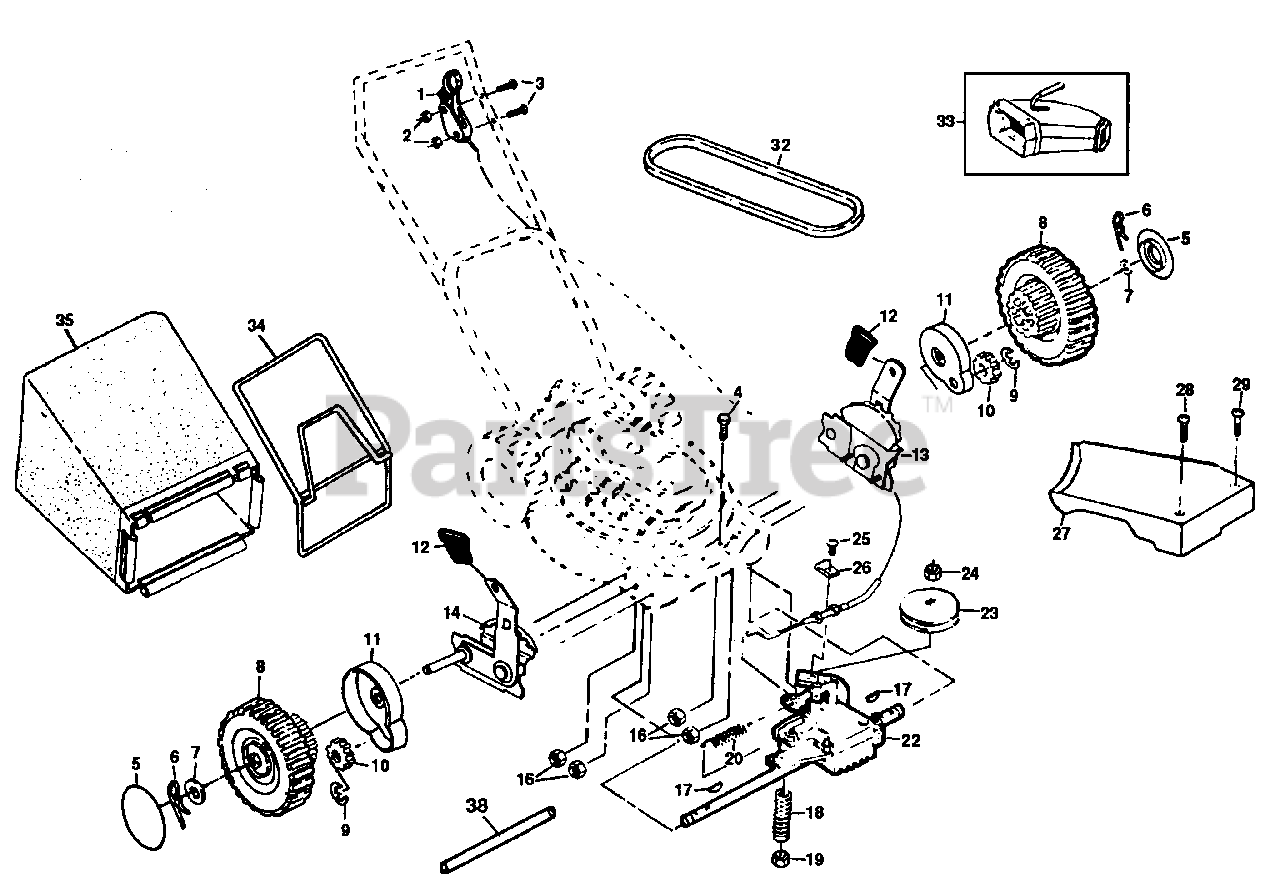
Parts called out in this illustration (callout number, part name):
1	Drive Control (AYP part number)
2	Locknut #10-24 (AYP part number)
3	Pan Head Machine Screw #10-24 x 2 (AYP part number)
4	Hex Head Bolt 1/4-20 x 2-3/4 (AYP part number)
5	Hubcap (AYP part number)
6	Retainer Clip (AYP part number)
7	Washer (AYP part number)
8	Wheel & Tire Assembly 8.00 x 1-3/4
10	Pinion (AYP part number)
11	Dust Cover (AYP part number)
12	Selector Knob
13	Wheel Adjuster Assembly (Left) (AYP part number)
14	Wheel Adjuster Assembly (Right) (AYP part number)
16	Locknut (AYP part number)
17	Woodruff Key #3 (AYP part number)
18	Spring (AYP part number)
19	Locknut 1/4-20 (AYP part number)
22	Gear Case Assembly (AYP part number)
23	Drive Pulley (AYP part number)
24	Locknut (AYP part number)
25	Pan Head Self-tapping Screw #10-24 (AYP part number)
26	Cable Clamp (AYP part number)
27	Drive Cover (AYP part number)
28	Pan Head Machine Screw #10-24 x 2-3/4 (AYP part number)
29	Pan Head Machine Screw #10-24 x 1-3/4 (AYP part number)
34	Frame Grass Bag 2-1/2 (AYP part number)
35	Grass Bag 2-1/2 Soft
38	Drive Shaft Cover (AYP part number)
